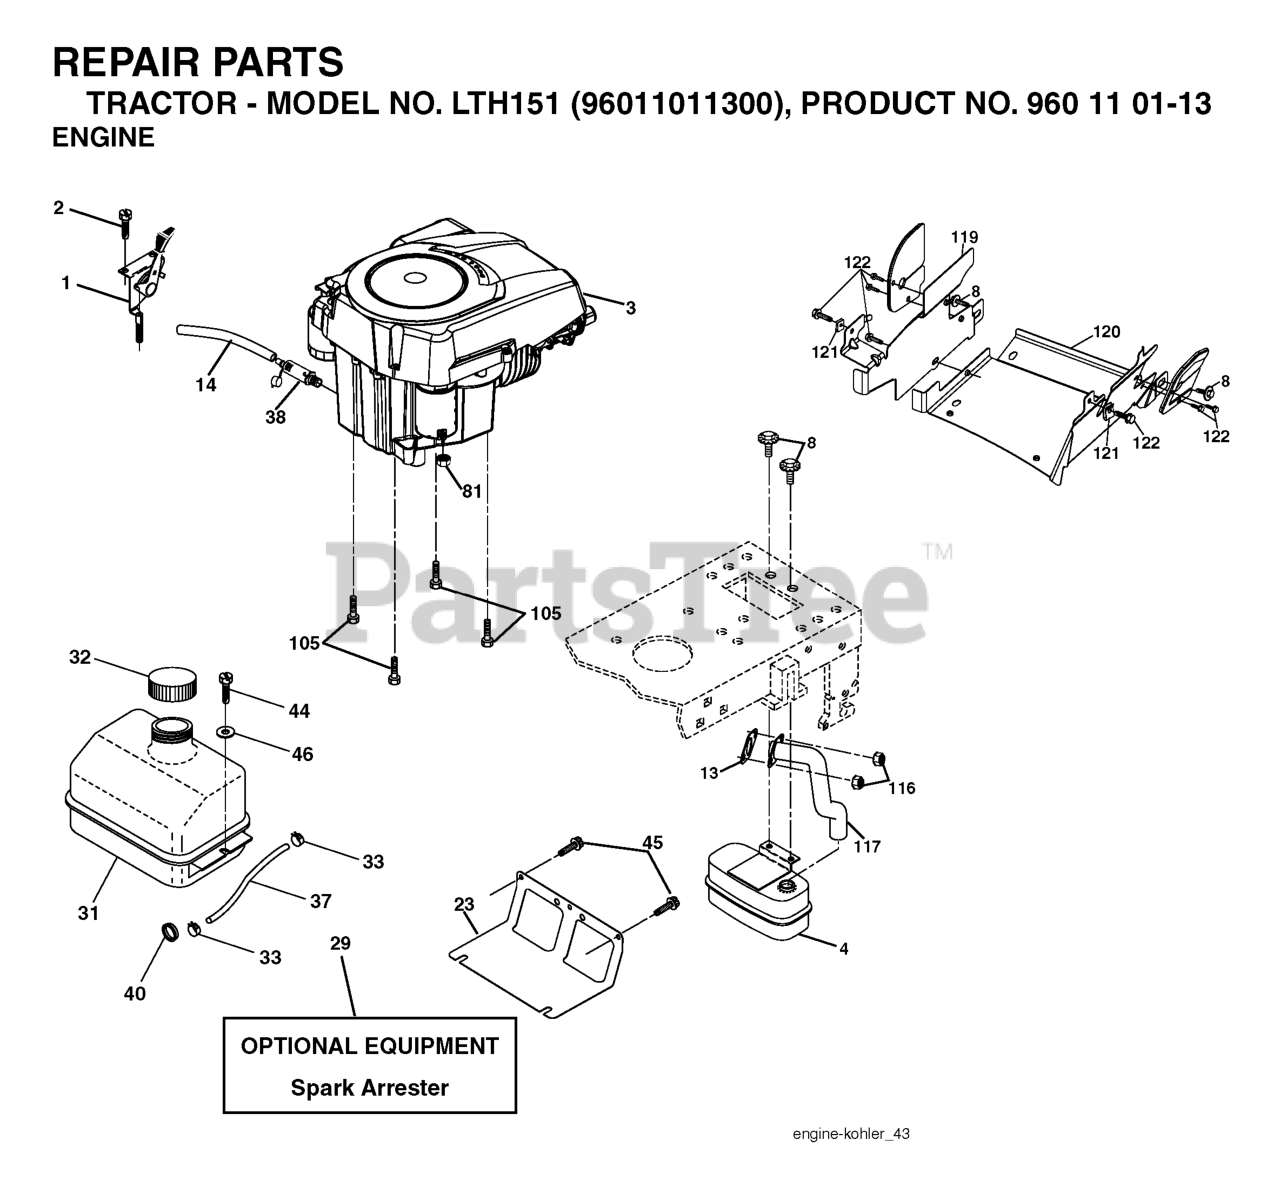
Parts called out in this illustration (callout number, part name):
1	CONTROL.THROTTLE.LT/YT
2	SCREW
4	MUFFLER.SINGLE.CYL.KOHL/B&S
8	BOLT.5/16-18UNCX3/4 W/SEMS.BLK
13	GASKET.EXHAUST.KOHLER
14	TUBE, DRAIN OIL ASM.
23	SHIELD.BROWNING.DBR.GUARD
29	KIT.SPARK ARRESTOR 794945 B&S
31	TANK.ASM.FUEL.FRONT.W/CAP
32	FUEL CAP
33	HOSE CLAMP
37	LINE.FUEL.20
38	PLUG DRAIN OIL EASY
40	BUSHING.SNAP.NYL.BLK.
44	SCREW HEXWSHR 1/4-20X3/4
45	SCREW, 3/8-16X3/4
81	NUT
105	SCREW 3/8-16X1
116	NUT.HEX.FLANGE.TOPLOCK
117	RP.TUBE.EXHAUST.KOHL.COURAGE
122	SCREW.1/4-20X5/8
123	SCREW, 5/16-18 X 1/2
